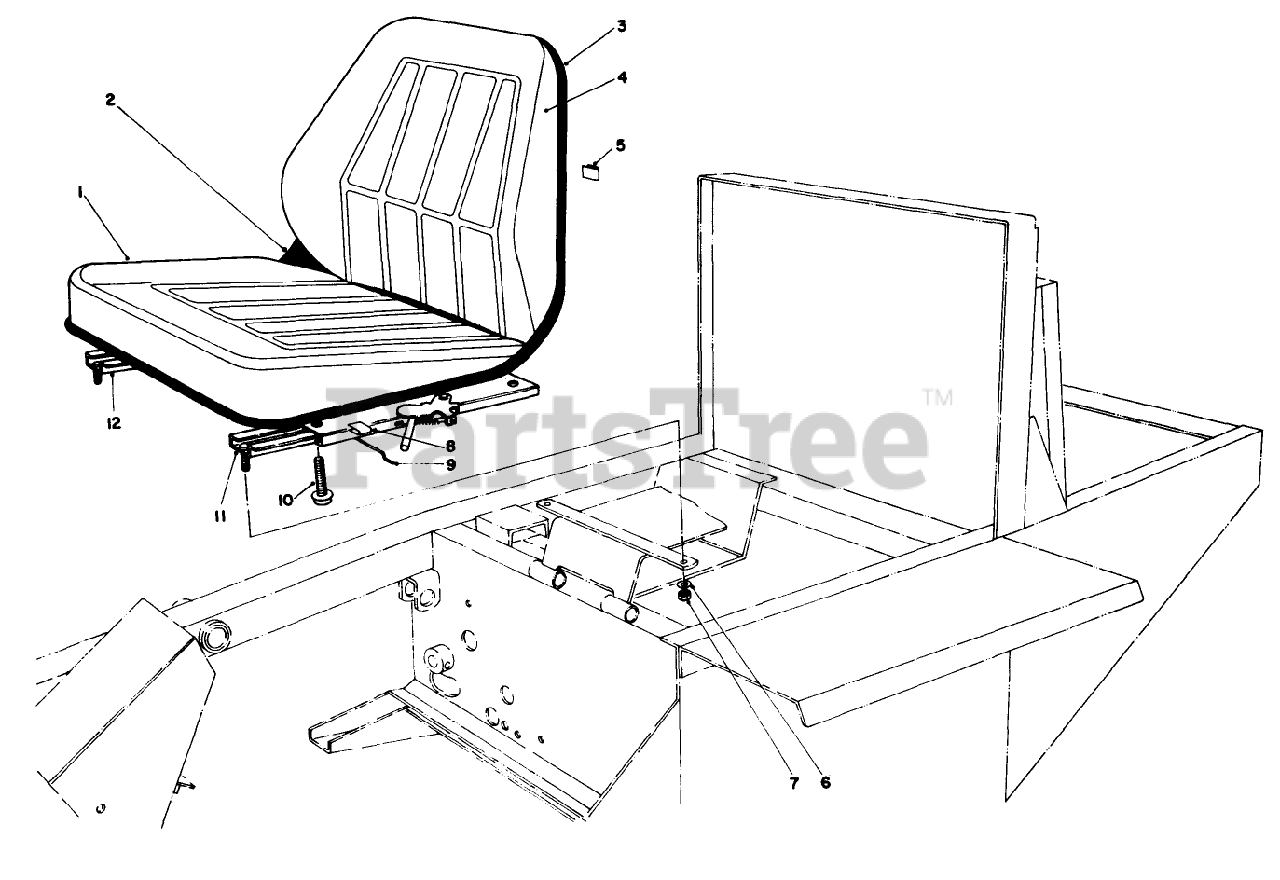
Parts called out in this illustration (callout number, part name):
1	Seat-Cushion (Incl. Ref.#5 & 8)
2	Shell
3	EDGING
4	Backrest (Incl. Ref.#5 & 8)
6	WASHER-LOCK
7	NUT-HEX
9	ROD-CONNECTING
10	SCREW-HHF
11	ADJUSTER-SEAT, LH
12	ADJUSTER-SEAT, RH
